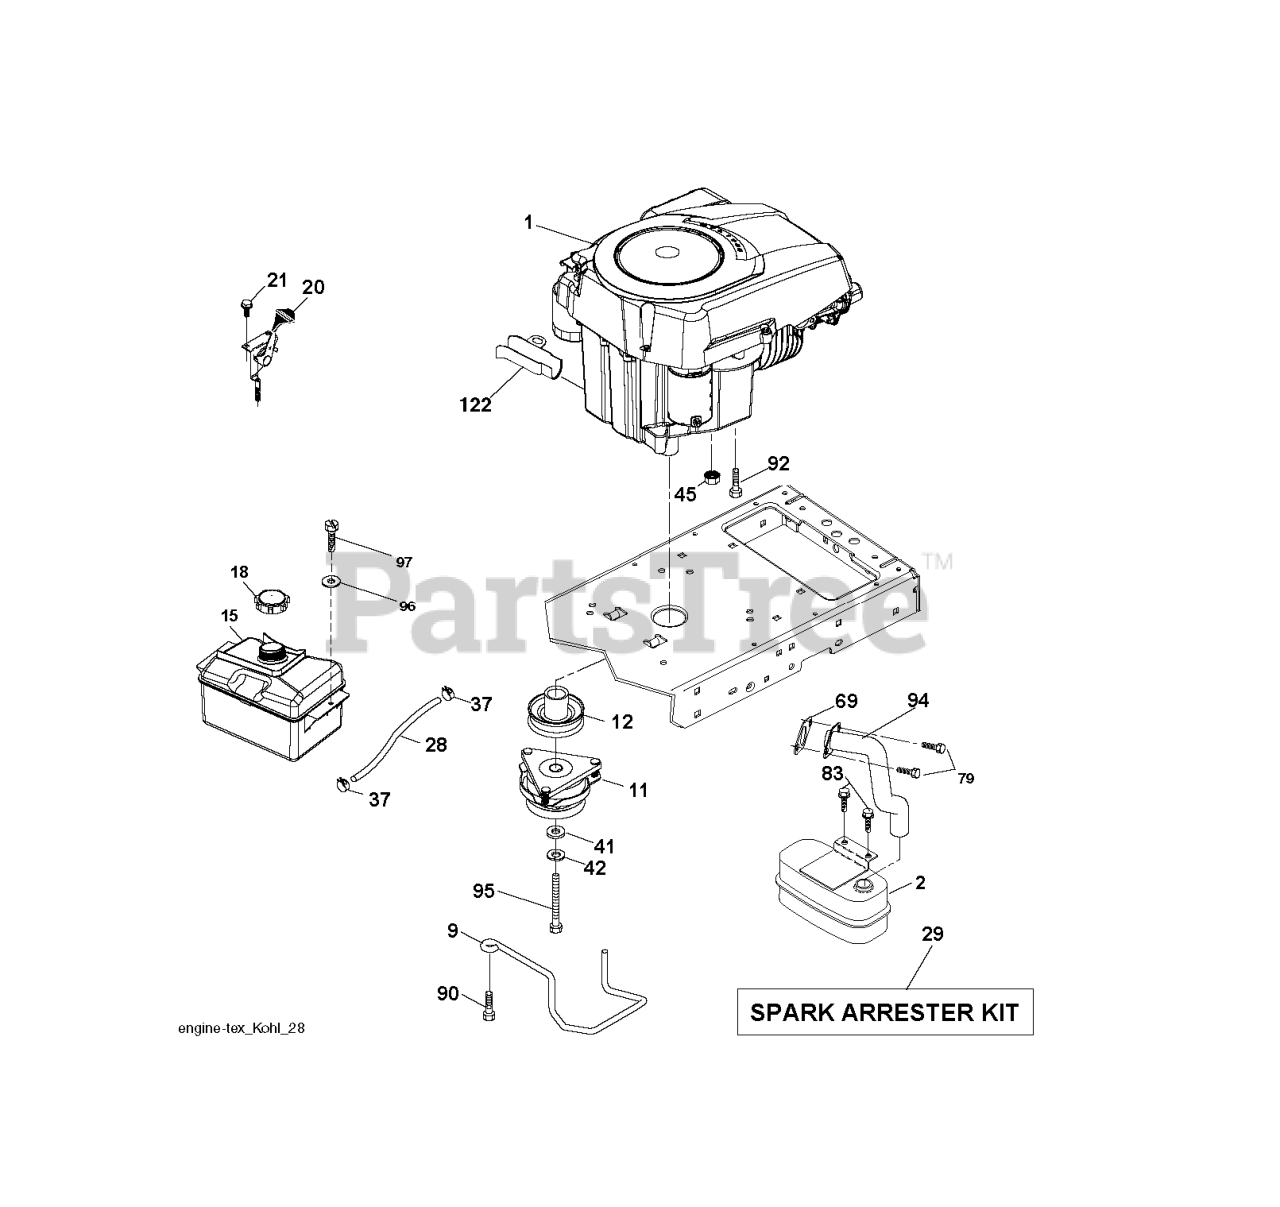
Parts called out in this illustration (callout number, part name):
2	MUFFLER.SINGLE.CYL.KOHL/B&S
9	KEEPER.BELT.ENGINE.4.2
11	RB.CLUTCH.OGURA.4.4.PD
12	PULLEY.ENGINE.TUFFTORQ
15	RP TANK FUEL FRT 1.5 GAL
18	CAP ASM.FUEL.2.25"FR.
20	CONTROL.TH/CK.C.
21	SCREW.#10 X 0.750.BOS
28	LINE.FUEL.20
29	KIT.SPARK ARRESTOR 794945 B&S
37	HOSE CLAMP
42	LOCKWASHER
45	NUT
69	GASKET.EXHAUST.KOHLER
79	SCREW.SOCKET HD.5/16-1
83	BOLT.5/16-18UNCX3/4 W/SEMS.BLK
90	SCREW 3/8-16X1
92	SCREW 3/8-16X1
94	RP.TUBE.EXHAUST.KOHL.COURAGE
95	BOLT HEX 7/16-20X4-1/4"
97	SCREW HEXWSHR 1/4-20X3/4
122	EXTENSION DRAIN OIL
